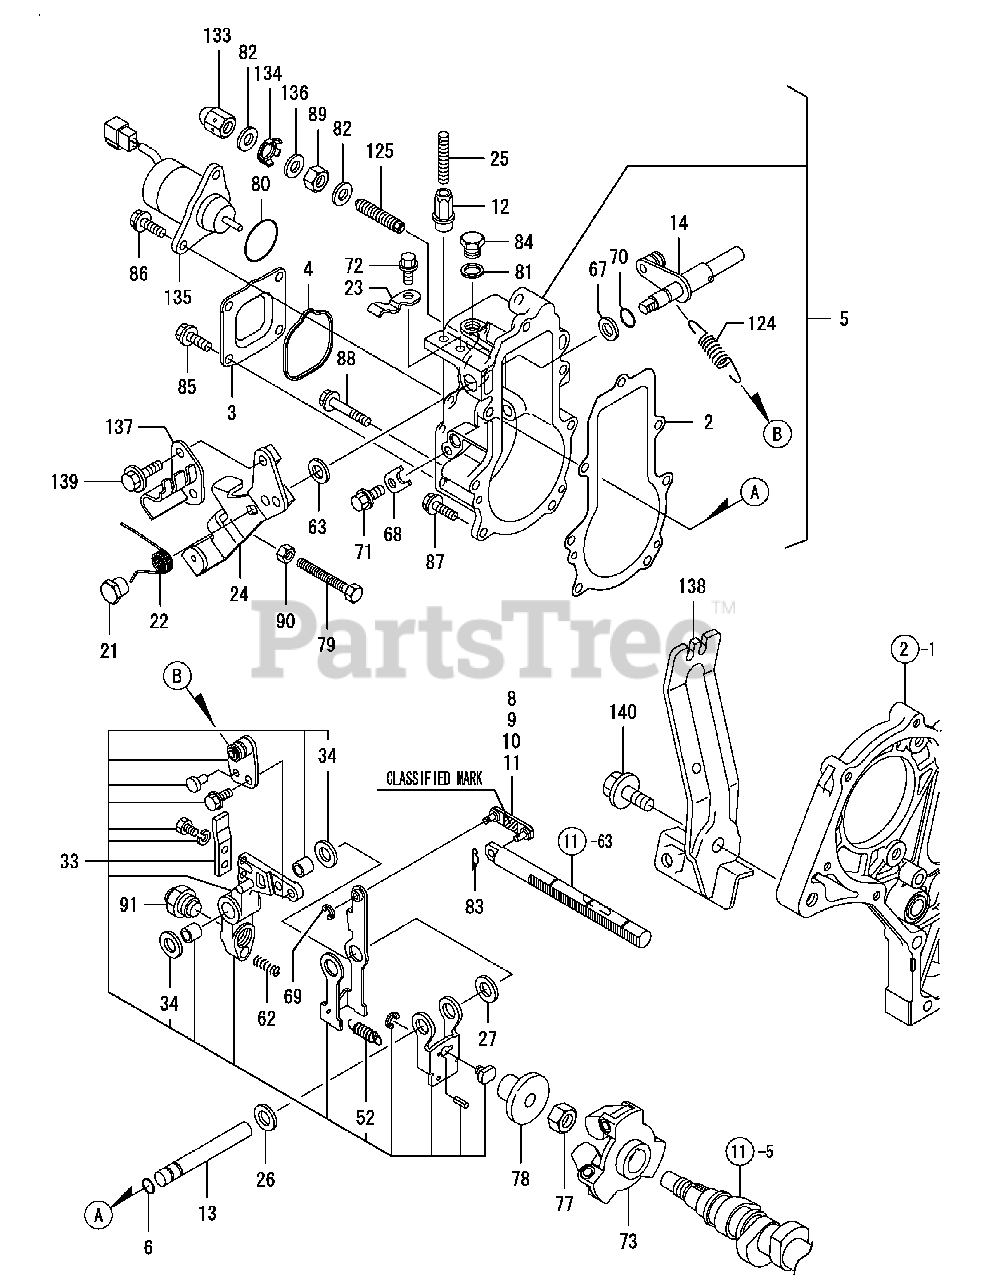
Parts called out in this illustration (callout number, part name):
3	CASE, GOVERNOR
4	GASKET, COVER
5	CASE ASSY, GOVERNOR
8	LINK, L=29.3 :3
9	LINK, L=29.8 :98
10	LINK, L=28.8 :88
11	LINK, L=30.3 :03
13	SHAFT, GOV. LEVER
14	SHAFT ASSY, CONTROL
24	LEVER, CONTROL
25	BOLT, REVOL. LIMIT
33	LEVER ASSY, GOVERNOR
62	SPRING, FUEL CONTROL
68	RETAINER, SHAFT
70	O-RING 1A S-7.0
71	BOLT 6X 10 PLATED
72	BOLT 6X 10 PLATED
77	NUT, GOVERNOR WEIGHT
78	SLEEVE(L=25.5)
79	BOLT, IDLE LIMIT
81	SEAL WASHER 10S
82	SEAL WASHER 12
85	BOLT 6X 10 PLATED
86	BOLT M 6X 14 PLATED
87	BOLT M 6X 20 PLATED
88	BOLT M 6X 45 PLATED
124	SPRING, GOVERNOR
125	LIMITER ASSY, FUEL
135	SOLENOID, STOP
137	HOOK ASSY, ACCELERATOR
138	SUPPORT, ACCEL WIRE
139	BOLT M 6X 12 PLATED
140	BOLT M10X 20 PLATED
